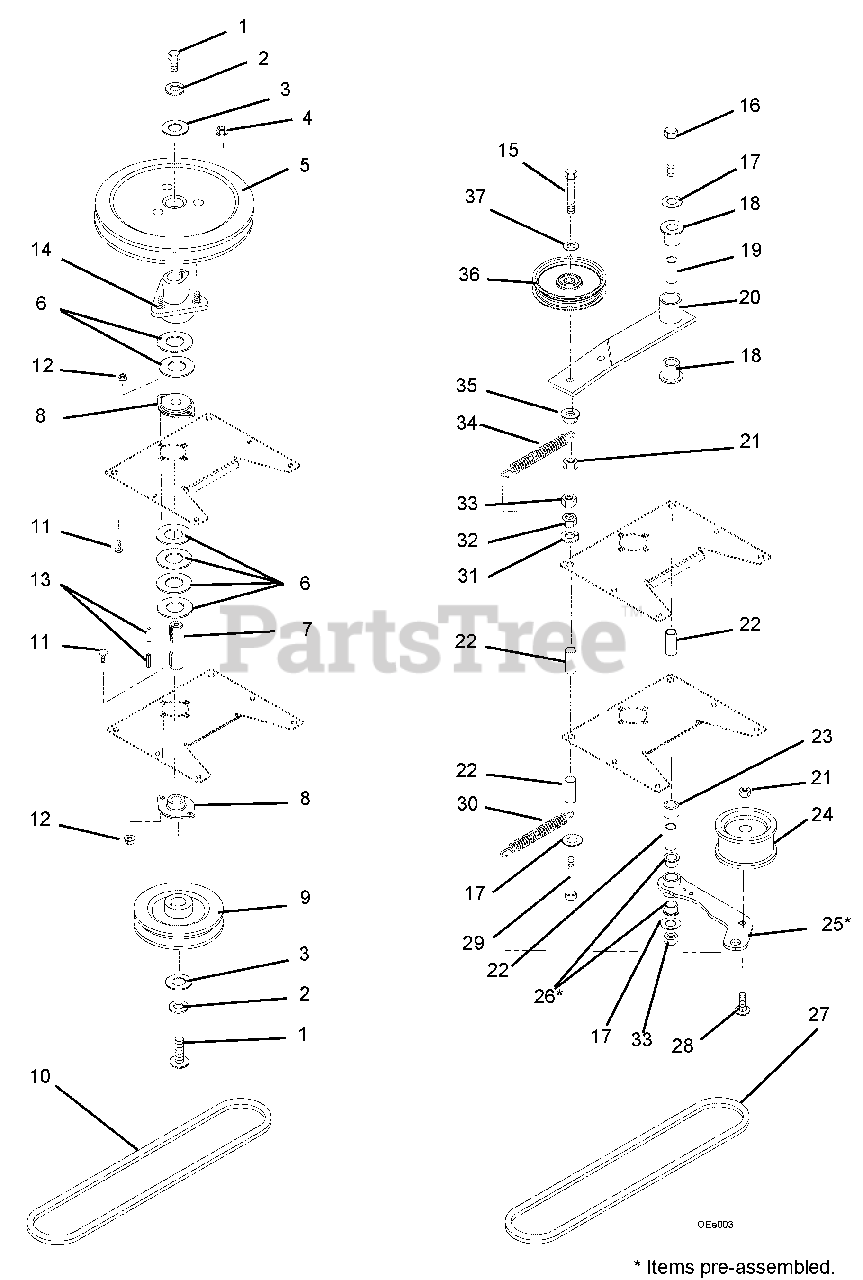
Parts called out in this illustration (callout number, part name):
1	@BLT-HEX .25-20X.75 GR5 YWZC
2	@WSHR-LK .25X.062 REG YWZC
3	WSHR-FL-STL .344X1.125X.135
4	@NUT-SPNLK-FLG .312-18 YWZC
5	PLY-V 9.0 X 1.25 3BLT
6	WSHR-FL-STL .755X1.25X.125 YZ
7	SHAFT,ZOOM SNO-THRO
8	BEARING, 2 BOLT FLANGE -.75 ID
9	SHEAVE, BLOWER - 4.25 DIA.
10	V-BELT, 4L-RAW EDGE
11	@BLT-RDHDSQNK .31-18X.75 G5YZ
12	@NUT-LK-TOP-FLG .31-18 YWZC
13	KEY-SQ .187 X .50 X .187
14	24389 HUB ASSEMBLY
15	@BLT-HEX .38-16X2.25 GR5 YWZC
16	BLT-HEX .50-13X7.00 GR5 YWZC
17	@WSHR-FL-STL.531X1.06X.095YWZC
18	BSHG-FLG .762X1.0X.580X1.48 NY
19	BUSH.,S.560X.745X2.04 ST
20	WMT,IDLER
21	@NUT-LK-CTR-JAM .375-16 YWZC
22	BSHG-SLV .500X.750X1.560
23	BUSHING, .516X1.000X1.050 LG
24	IDLER FLANGED 3.50
25	WMT, IDLER ARM
26	BSHG-FLG 0.75X0.875X.625X1.125
27	V-BELT, HA-WRAPPED
28	@BLT-RDHDSQNK .38-16X1.75 G5YZ
29	@BLT-HEX .50-13X5.00 GR5 YWZC
30	SPRING, EXTENSION
31	@WSHR-LK .50X.125 REG YWZC
32	@NUT-HEX .50-13 YWZC
33	NUT-LK-CTR-JAM .50-13 YWZC(ND)
34	SPRING, EXT
35	@NUT-SPNLK-FLG .375-16 YWZC
36	PULLEY, IDLER 4.00
37	@WSHR-FL-STL.406X.812X.065 YWZ
